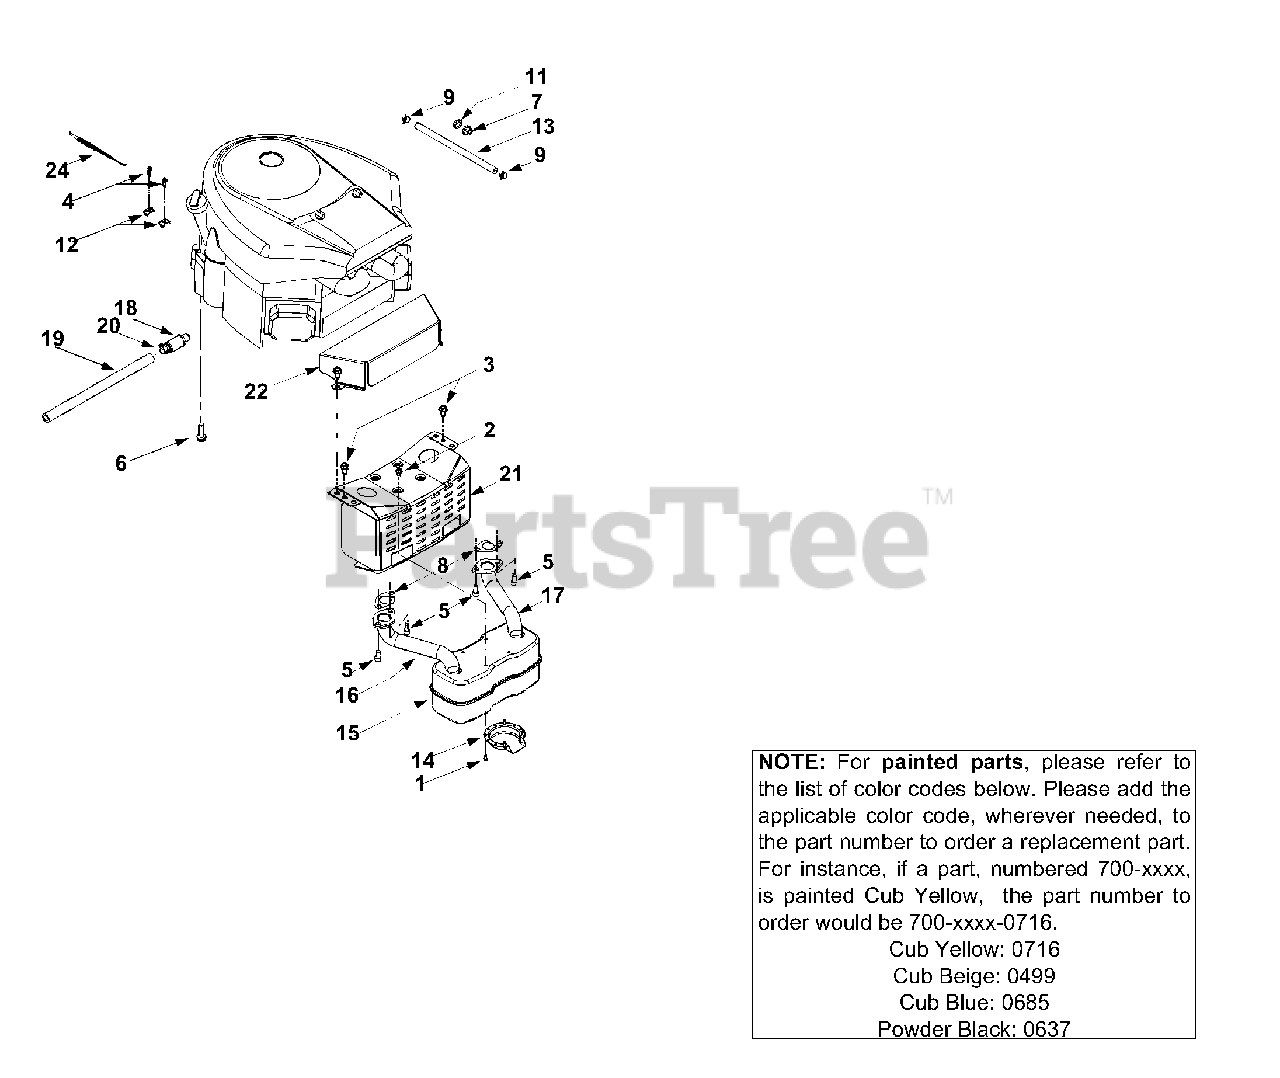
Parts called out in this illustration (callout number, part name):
1	Self-tapping Screw, #8-18 x .5
2	Self-tapping Screw, 1/4-20 x .5
3	Self-tapping Screw, 5/16-18 x .75
4	Screw, #10-32 x .625
5	Socket Cap Screw, 5/16-18 x .625
6	Self-tapping Screw, 3/8-16 x 1.25
7	Hex Nut, 3/8-16
8	Exhaust Gasket
9	Hose Clamp
11	Flat Washer
12	Casing Clamp
13	Fuel Line Hose
14	Muffler Deflector
15	Muffler, Twin Inlet
16	RH Exhaust Pipe
17	LH Exhaust Pipe
18	Oil Drain Valve
19	Oil Drain Hose
20	Oil Drain Cap
22	Engine Heat Shield
24	Throttle Cable
